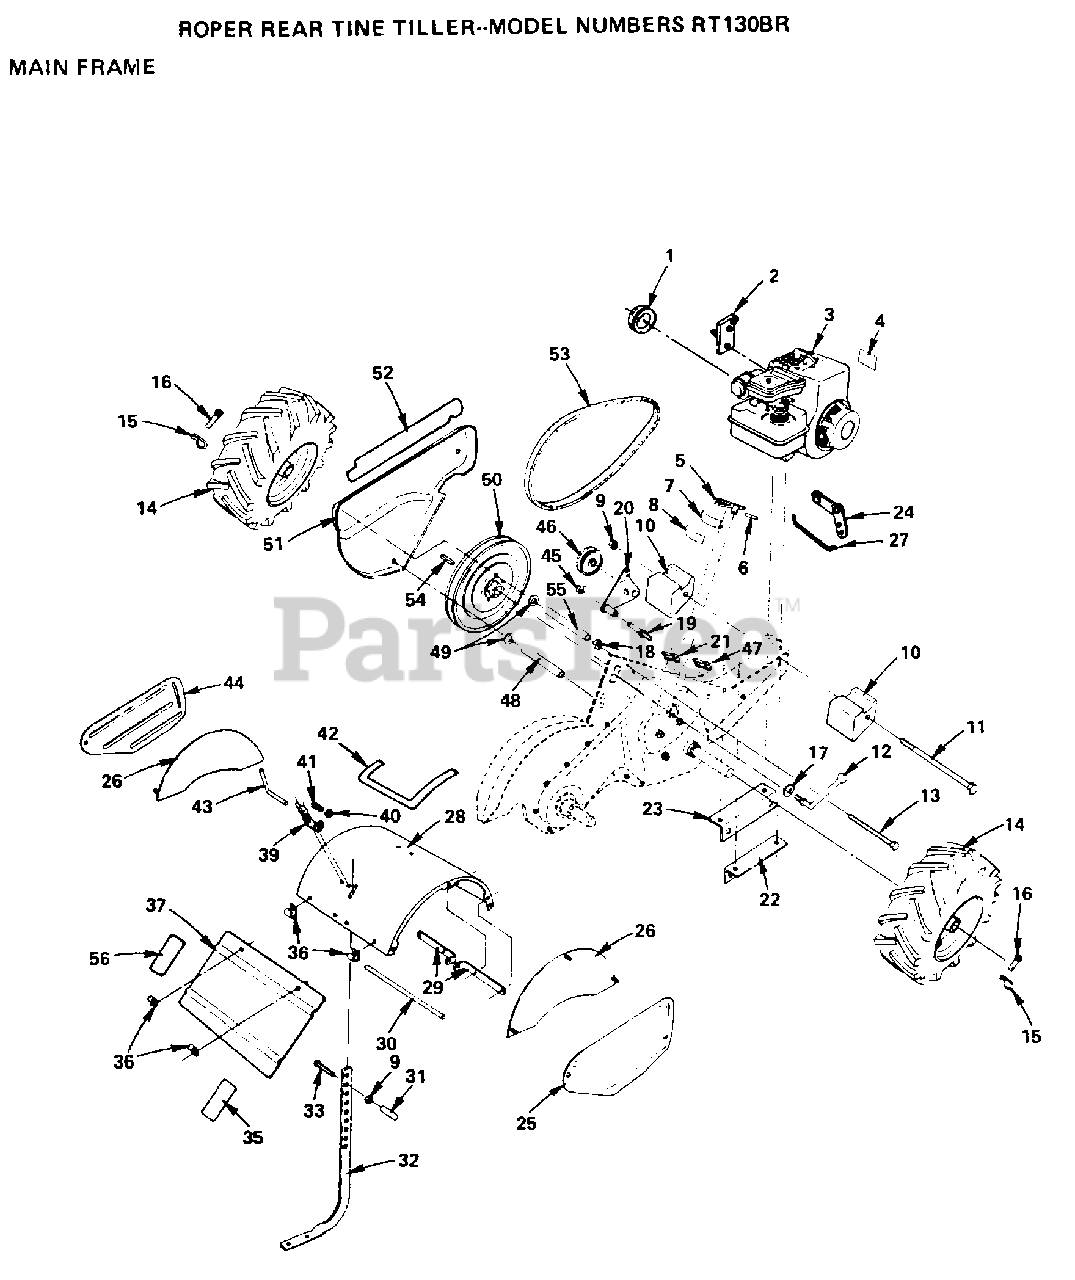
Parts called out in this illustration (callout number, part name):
2	BRACKET ASSY CRT
3	ENGINE, B&S
7	PANEL TI
8	DECAL CRT
9	NUT.HEX.3/8-16UNC
10	COUNTERWEIGHT CRT
11	BOLT CRT
13	BOLT-HEX TI
15	RETAINER M
17	WASHER
18	NUT.HEX.5/16-18
19	SHIFT ARM CRT
21	CONDIUT CLIP T
22	BRACKET RH CRT
23	BRACKET LH CRT
31	GRIP CRT
33	BOLT
36	HINGE CRT
39	LATCH BRACKET TI
40	KLIP RING TI
41	SPRING TI
43	STAKE PIN TI
45	KLIP RING
46	PULLEY-IDLER TI
47	CLAMP
49	WASHER
50	"SHEAVE 10"" CRT"
52	DECAL - BELT GUARD
54	KEY T
56	DECAL - DEPTH ADJUSTMENT
